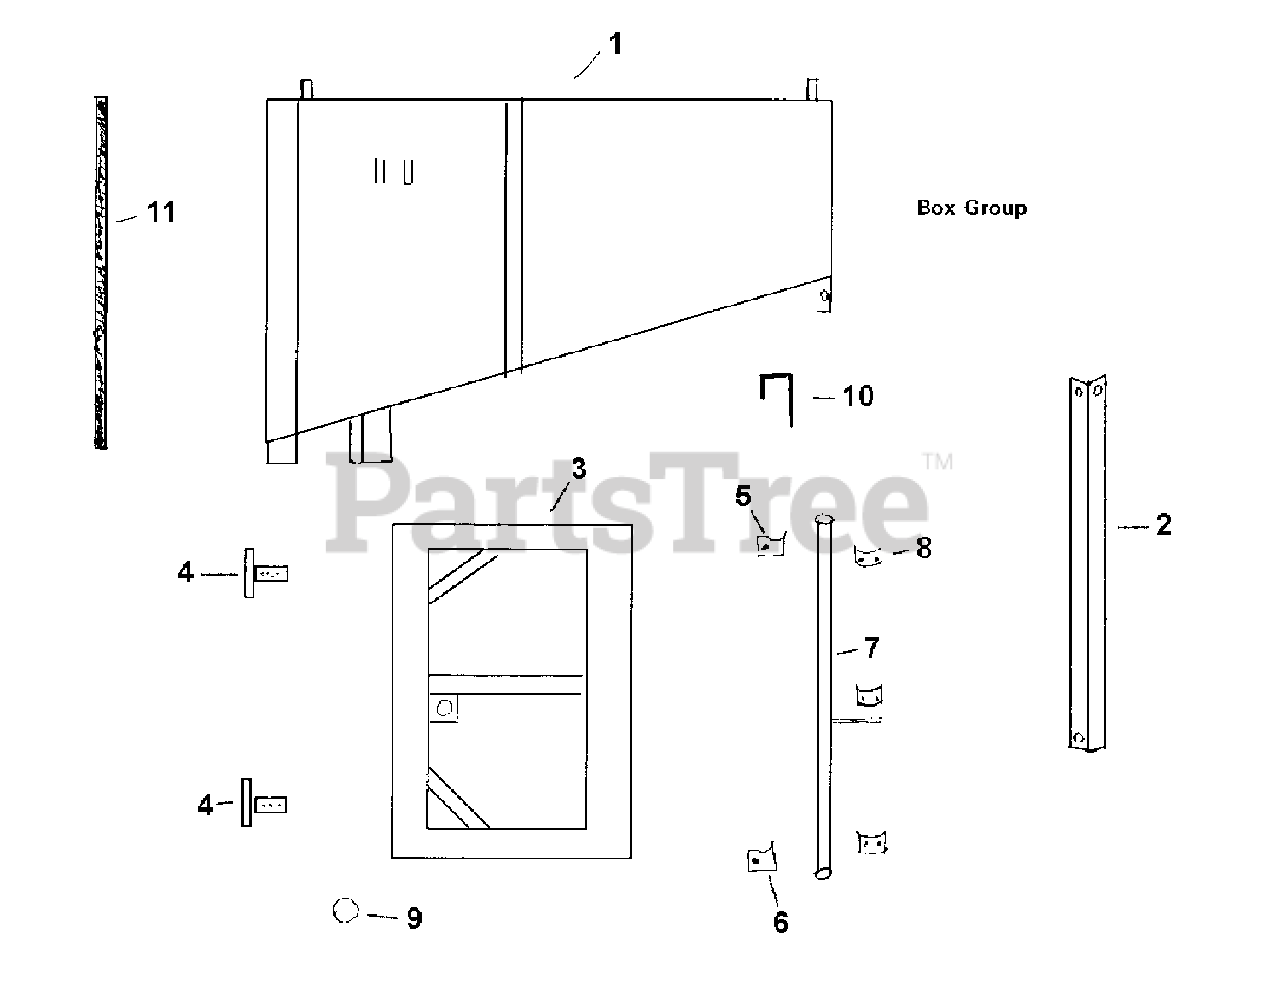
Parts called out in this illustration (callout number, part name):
1	5 Yard Box
2	Box Support Left
2	Box Support Right
3	Barn Type Rear Door Left
3	Barn Type Rear Door Right
4	Door Hinge
5	Door Lock Top
6	Door Lock Bottom
7	Door Rod Left
7	Door Rod Right
8	Rod Holder
9	Stop & Tail Light Assembly
10	Door Retaining Rod
11	Door Gasket - 20 Feet
